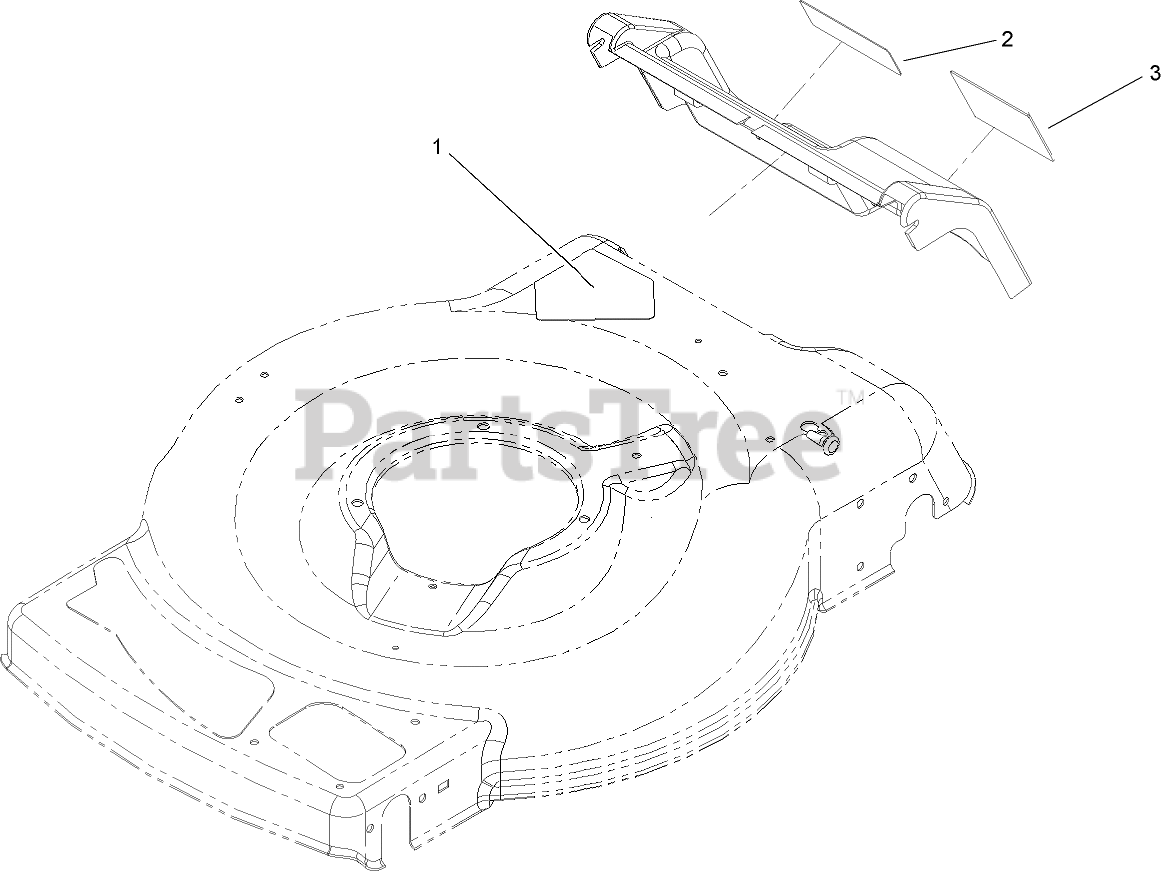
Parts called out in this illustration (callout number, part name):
1	DECAL-DANGER
2	DECAL-WARNING
3	DECAL-WARNING
